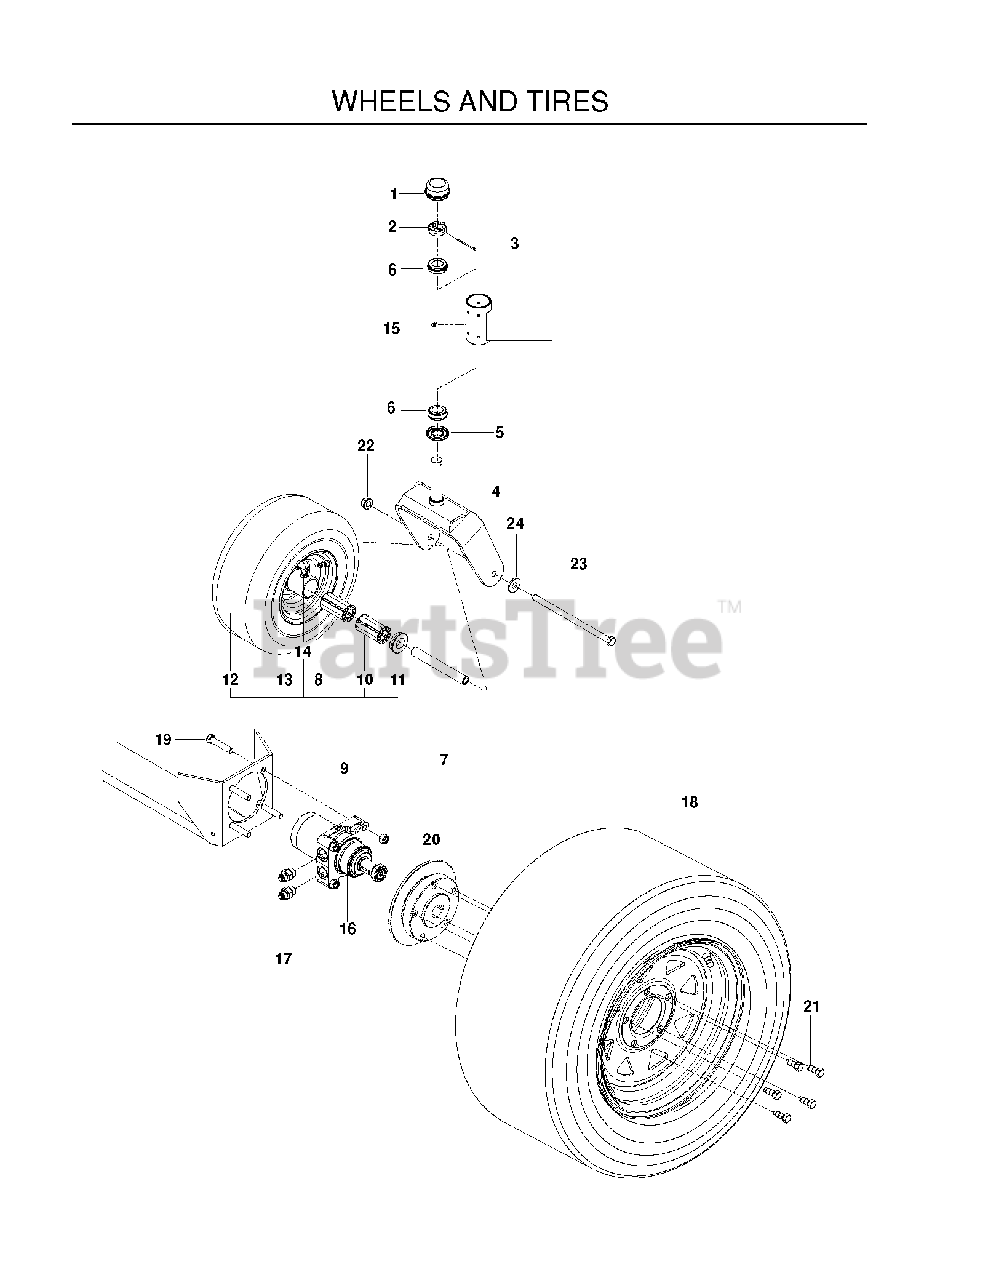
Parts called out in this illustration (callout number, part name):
1	GREASE CAP
2	NUT 1"C HEX SLOTTED
3	COTTER PIN 1/8 X 2
4	YOKE, CASTER, BLUE
5	TAPERED ROLLER BRG
7	SPACER, PIVOT
8	VALVE STEM TR-412
9	TIRE.ASSEM.CASTER.13X6.5-6.SIL
10	ROLLER BEARING-CAGED 3 1/4'
11	BEARING RETAINER
12	TIRE.13X6.50-6.4.PLY
13	WHEEL.6X4.50
14	ZERK
16	WHEEL MOTOR, TJ
17	CONNECTOR, STRAIGHT
18	WHEEL.R.TS.23X10.5-12.C.MS
19	HCS 1/2C X 2 3/4
20	NUT 1/2-13 HEX NYLOC ZD
21	HUB BOLT
22	NUT, 1/2-13 HEX FLG NYLOC ZD
23	HEX SCREW 1/2-13 X 9.5 GR5
24	WASH USS FLAT 1/2
